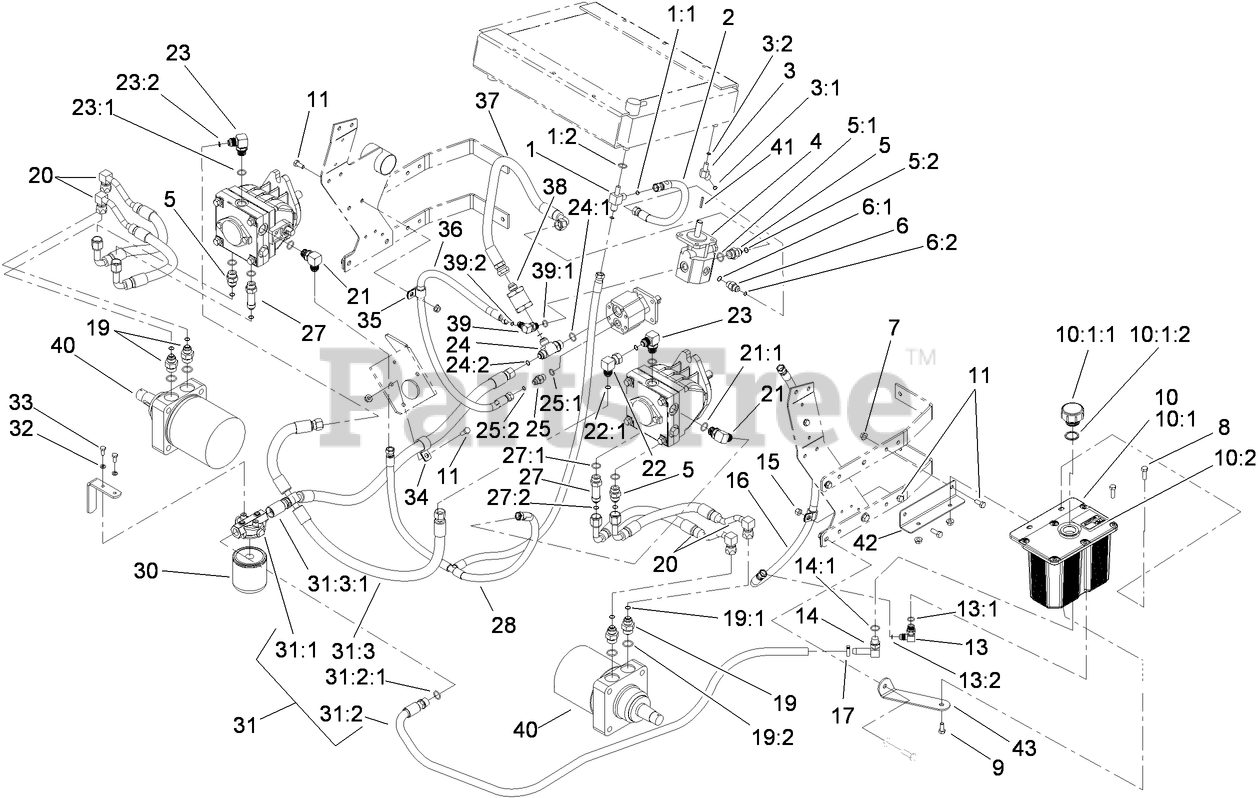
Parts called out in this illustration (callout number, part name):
1	FITTING-HYD, STRAIGHT TEE
1:1	O-RING
1:2	O-RING
2	FAN CASE DRAIN HOSE ASM
3	FITTING-HYD, 45 ELBOW
3:1	O-RING
3:2	O-RING
4	MOTOR-FAN, COOLING
5	FITTING-STRAIGHT
5:1	O-RING
5:2	O-Ring
6	FITTING-STRAIGHT
6:1	O-RING
6:2	O-RING
7	NUT-HF
8	SCREW-HH
9	SCREW-HH
10	HYDRAULIC TANK ASM
10:1	TANK-HYDRAULIC
10:1:1	CAP-RESERVOIR, HYD
10:1:2	GASKET-CAP
10:2	DECAL-TANK, HYD
11	SCREW-HH
13	FITTING-90 DEG
13:1	O-Ring
13:2	O-RING
14	FITTING-ELBOW, 90 DEG
14:1	O-RING
15	NUT-LOCK, NI
16	TANK RETURN HOSE ASM
17	CLAMP-HOSE
19	Fitting-Straight
19:1	O-RING
19:2	O-Ring
20	HYD HOSE ASM
21	FITTING-ELBOW, 90 DEG
21:1	O-RING
22	FITTING-90 DEG
22:1	O-Ring
23	FITTING-90 DEG
23:1	O-RING
23:2	O-Ring
24	FITTING-TEE
24:1	O-RING
24:2	O-Ring
25	FITTING-STRAIGHT
25:1	O-Ring
25:2	O-RING
27	ADAPTER-HYD, STRAIGHT
27:1	O-RING
27:2	O-Ring
28	CASE DRAIN HOSE ASM
30	FILTER-OIL, HYDRAULIC
31	CHARGE HOSE ASM
31:1	HEAD-FILTER
31:2	FILTER INLET HOSE ASM
31:2:1	O-RING
31:3	PUMP INLET HOSE ASM
31:3:1	O-RING
32	WASHER-LOCK
33	SCREW-HH
34	CLIP-LOOM
35	CLIP-LOOM
36	AUXILLARY PUMP HOSE ASM
37	HOSE-PRESSURE, HIGH
38	FILTER-IN LINE, 50 MICRON
39	FITTING-90 DEG
39:1	O-Ring
39:2	O-RING
40	MOTOR-WHEEL, HYD
41	KEY-SQUARE
42	BRACKET-TANK MOUNT, UPPER
43	BRACKET-TANK MOUNT, LOWER
